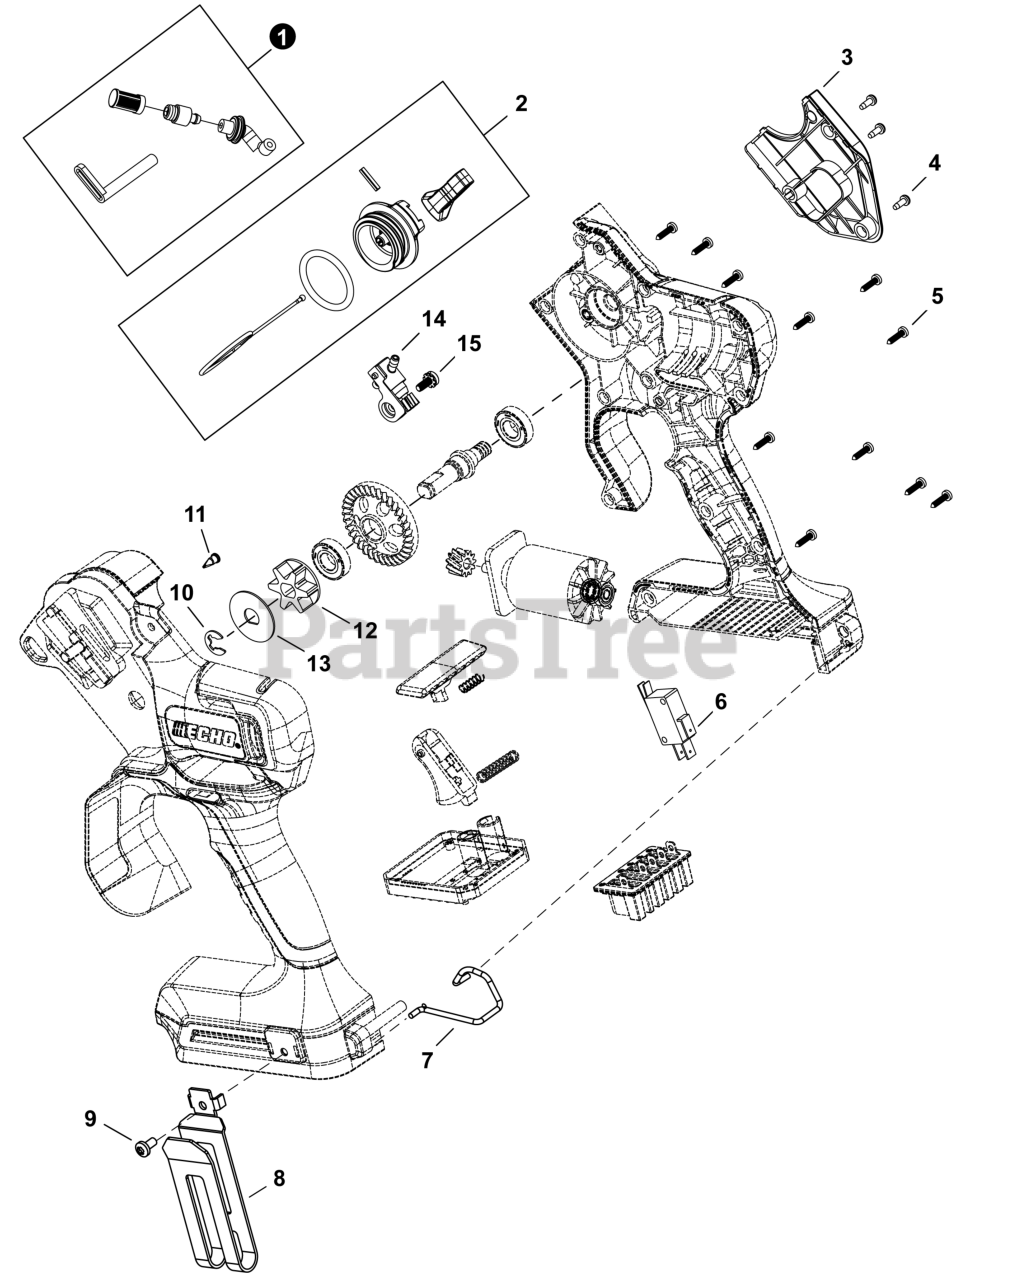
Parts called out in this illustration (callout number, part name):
1	HOSE KIT, OIL
2	CAP ASSY., OIL
3	COVER, OIL TANK
8	HOOK, BELT
11	VALVE, AIR VENT
12	SPROCKET
13	WASHER, SPROCKET
14	OIL PUMP ASSY
